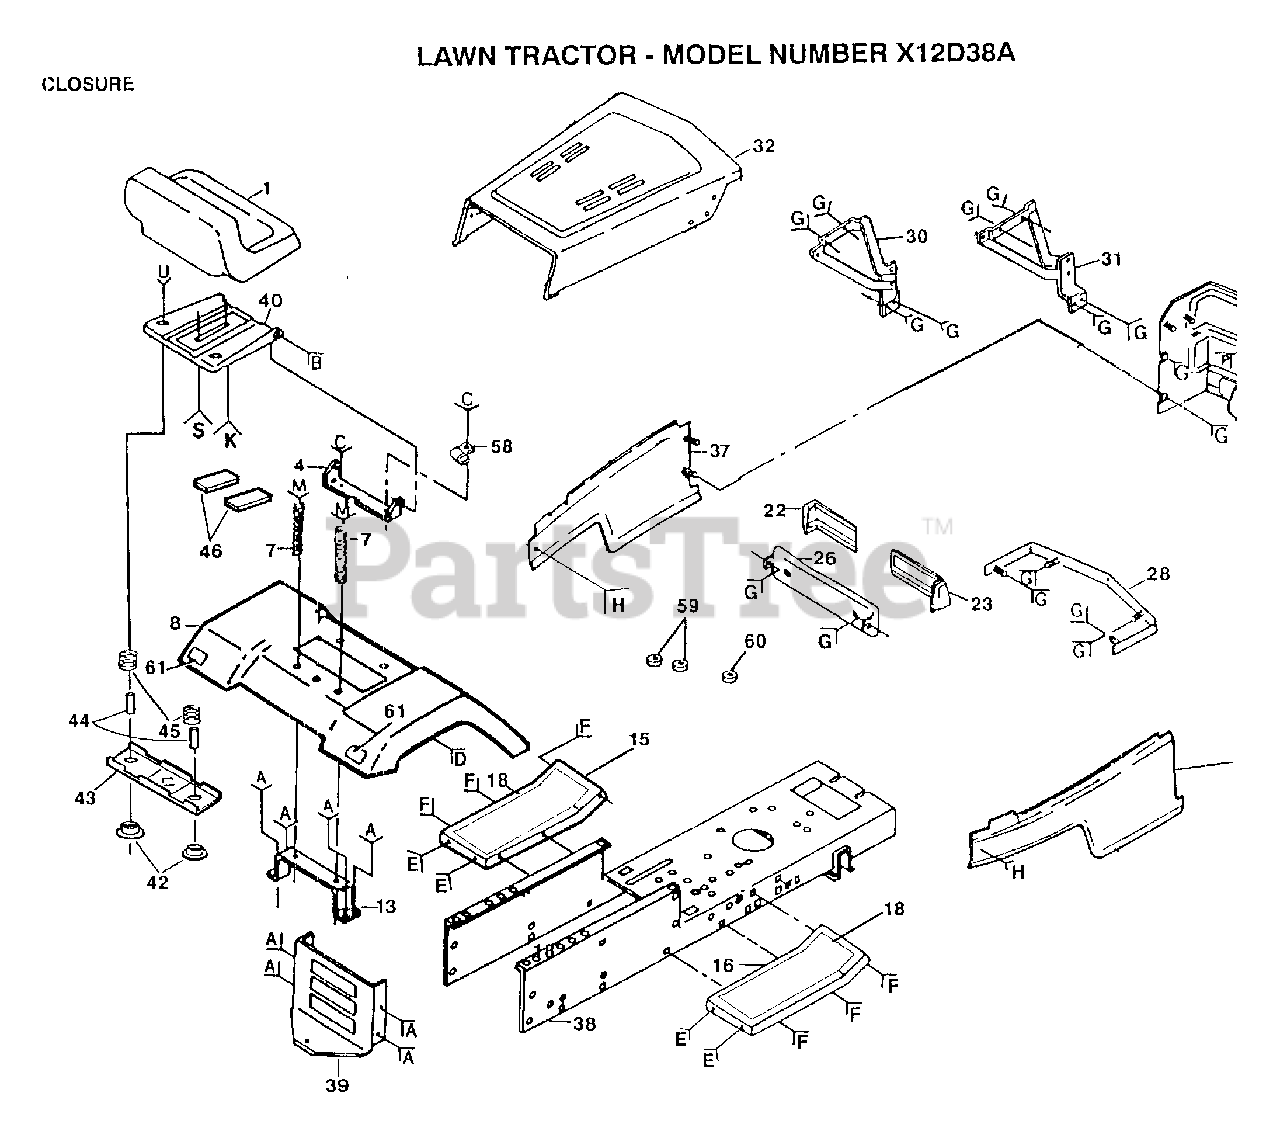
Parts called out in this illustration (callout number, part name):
7	SPRING COMPRESSIO
18	"PAD,FOOTREST"
30	"HINGE,HOOD,LH T"
31	"HINGE,HOOD,RH T"
37	"SIDE PANEL,LH"
38	CHASSIS ASS'Y
43	BRKT SWITCH
44	SPACER SPLIT
45	SPRING
46	STRIP FORM
61	REFLECTOR-TAIL YT
